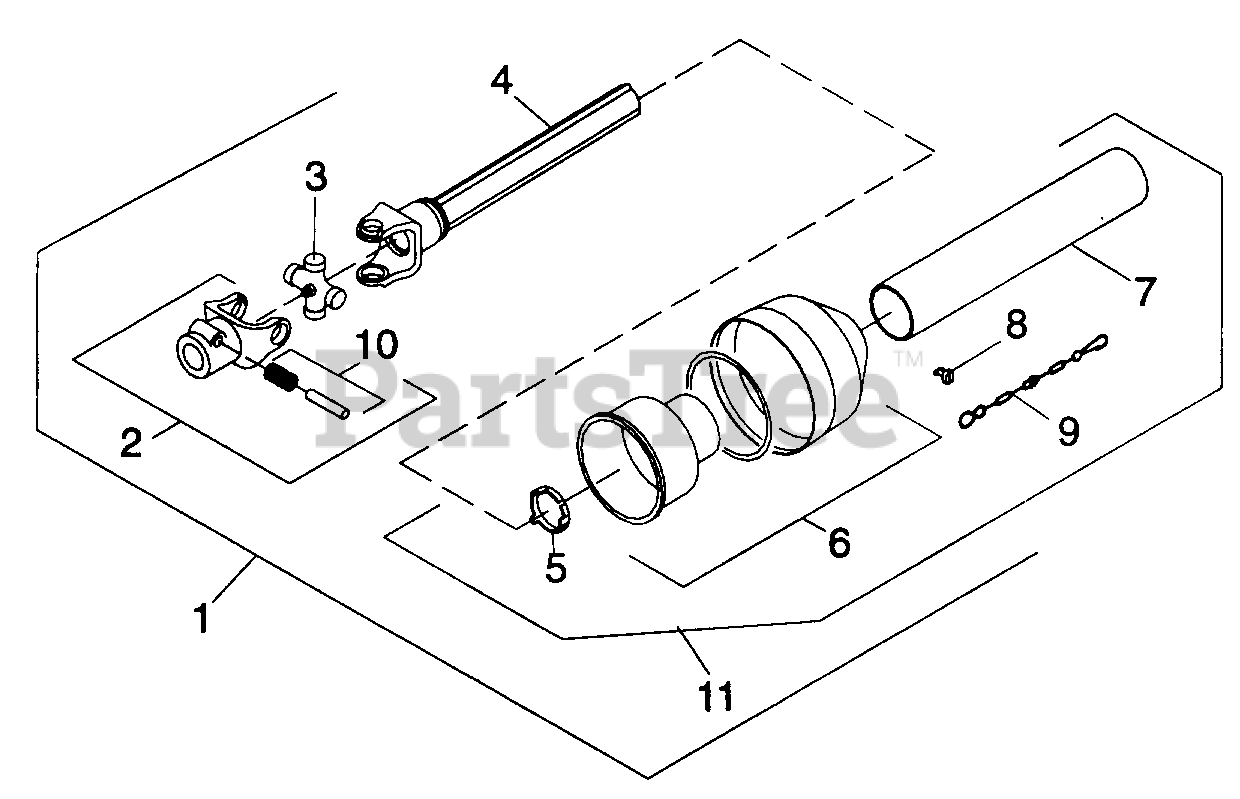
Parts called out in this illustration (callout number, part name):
1	Profile - shield drive 40, 25.8, 1.38
2	40 QD yoke
3	U-Joint repair kit 40S
4	Yoke and tube (Profile) 40 x 25.8
5	Drive shield bearing 40
9	Shield tether chain
10	40S QD Repair kit
11	Outer shield assembly complete
